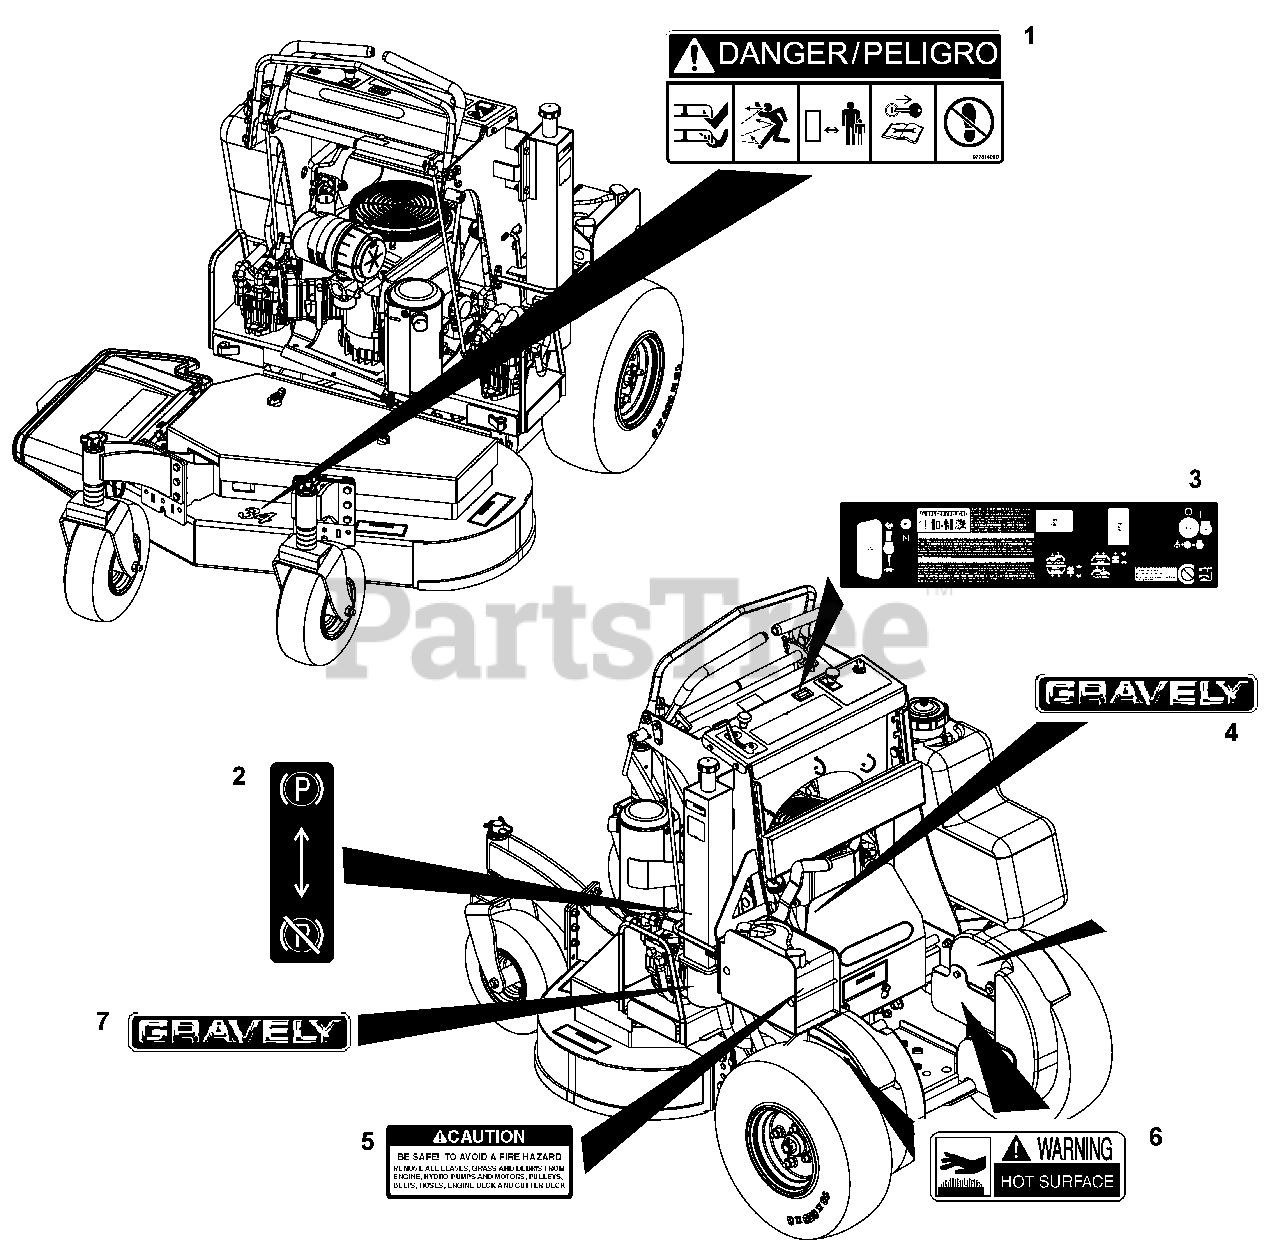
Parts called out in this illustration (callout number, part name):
1	Decal, Danger - Blade Contact
2	Decal, Park Brake
3	Decal, Console
4	Decal, 15" Gravely Logo
5	Decal, Caution - Fire Hazard
6	Decal, Warning, Hot Surface
7	Decal, Gravely Logo
